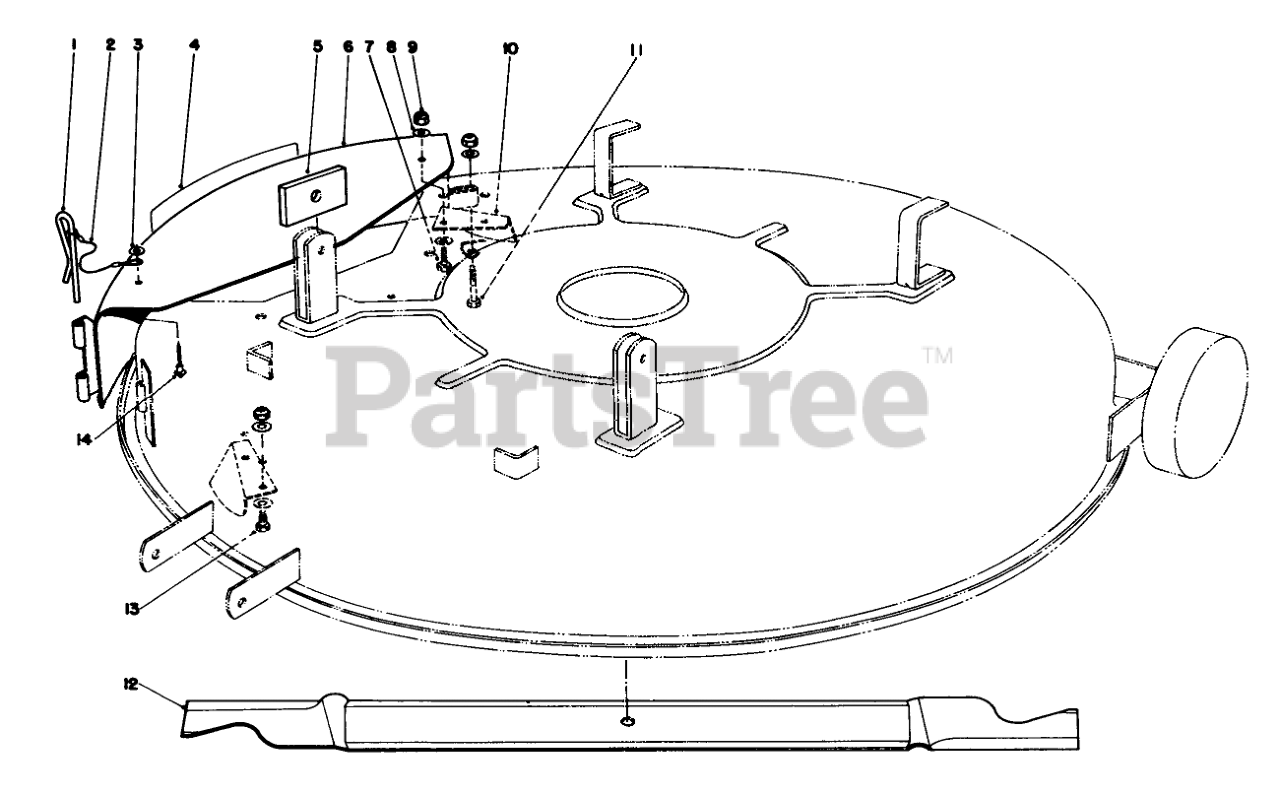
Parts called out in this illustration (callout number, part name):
1	PIN-LOCKING, CHUTE
2	LANYARD
3	WASHER-PLAIN
4	COVER DECAL
5	SPACER
6	Cover-Mulcher Assembly (Incl. Ref. #1-4&14)
7	SCREW-HH
8	WASHER-PLAIN
9	NUT-LOCK, NI
10	KICKER B
11	SCREW-HH
12	Blade
13	SCREW-HH
14	RIVET-BLIND
